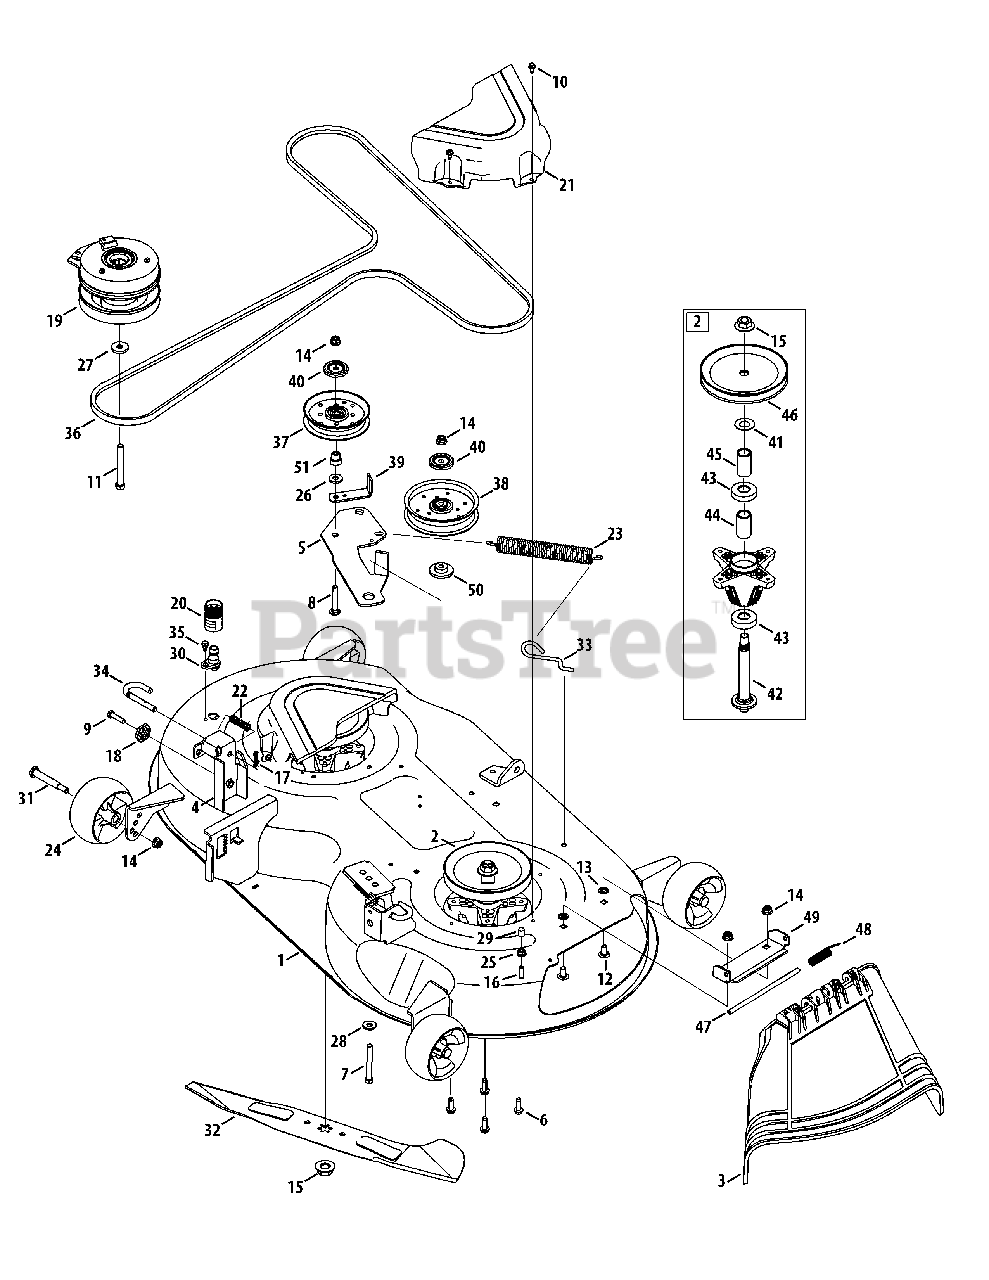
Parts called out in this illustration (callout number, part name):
1	46"Deck
2	Spindle Assembly
3	Chute Deflector Assembly
4	Deck Lift Bracket
5	Idler Bracket
6	Hex Washer Head Screw 5/16-18 x .75
7	Hex Cap Screw 3/8-16 x 3.5
8	Carriage Screw 3/8-16 x 1.75
9	Hex Cap Screw 5/16-18 x 1.25
10	Hex Washer Screw 1/4-20 x .625
11	Screw 7/16-20 x 3.25
12	Carriage Screw 3/8-16 x .75
13	Push Nut 3/8
14	Flange Lock Nut 3/8-16
15	Hex Flange Nut 5/8-18
16	Hex Cap Screw 5/16-18 x 1.00
17	Cotter Pin 3/32 x 1.25
18	Deck Adjustment Gear
19	Electric PTO Clutch
20	Water Nozzle Adapter
21	Belt Cover
22	Compression Spring .66 x 1.9
23	Extension Spring 1.25 OD x 1.751
24	Deck Ball Wheel 5.0
25	Flange Lock Nut 5/16-18
26	Flat Washer .385 x .870 x .092
27	Flat Washer .450 x 1.25 x .164
28	Flat Washer .406 x 1.00 x .105
29	Cap .290 x .500
30	Deck Wash Nozzle
31	Shoulder Screw .5 x 2.5 x 3/8-16
32	Blade 2 in 1 23.25
33	Deck Spring Rod
34	Deck Hanger Rod
35	Shoulder Screw .500 x 1/4-20
36	V-Belt
37	Idler Pulley 4.25 Dia.
38	Idler Pulley 5.00 Dia.
39	Bracket Belt Guard
40	Pulley Cap
41	Washer .760 x 1.50 x .030
42	Spindle Shaft
43	Ball Bearing
44	Spacer .792 x 1.060 x 1.860
45	Spacer .8 x 1.1 x 2.26
46	Deck Pulley
47	Hinge Pin
48	Torsion Spring
49	Chute Bracket
50	Shoulder Spacer
51	Shoulder Spacer
